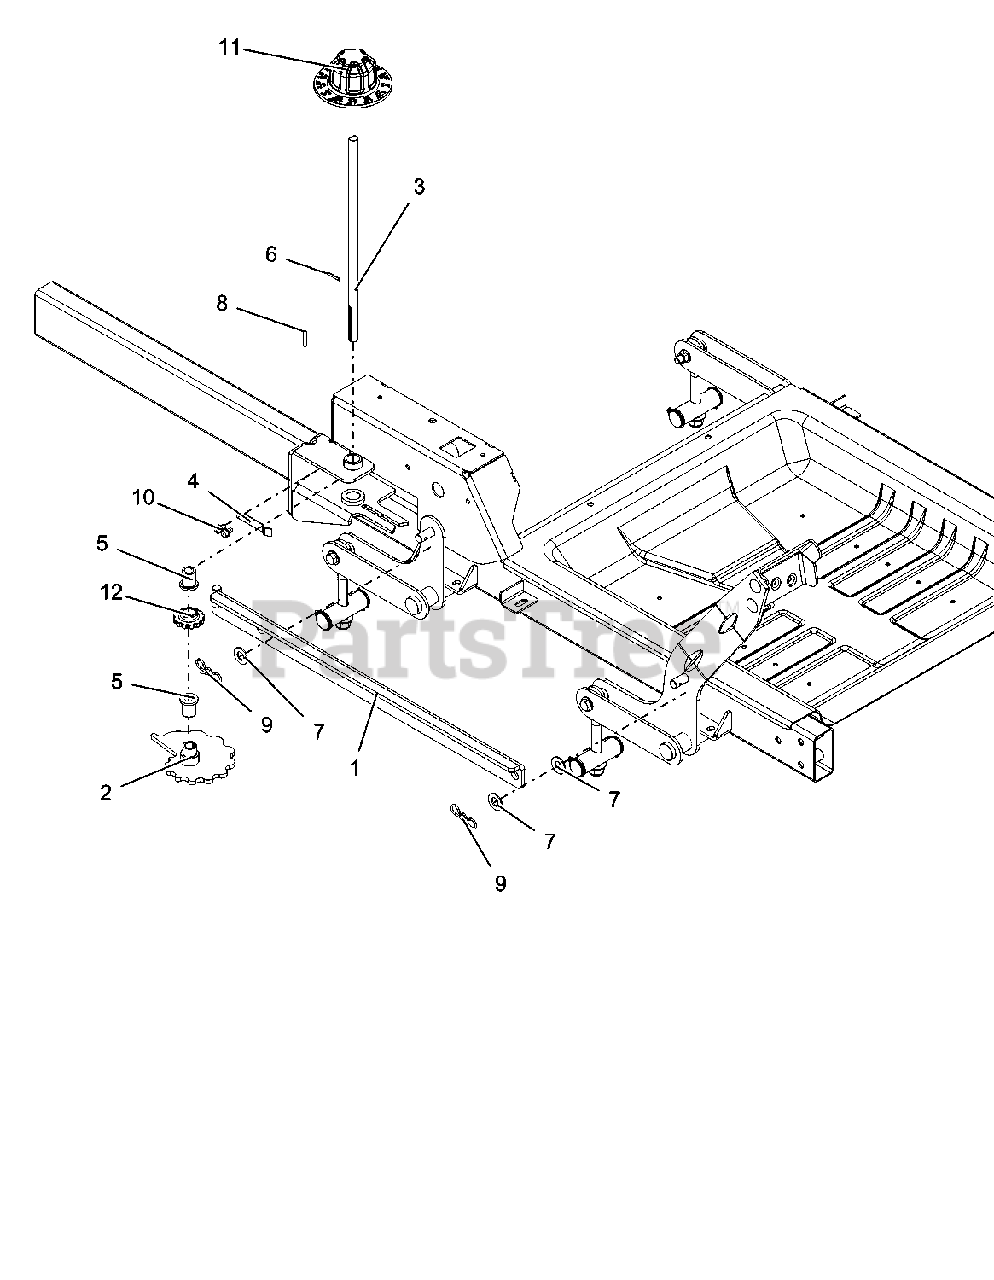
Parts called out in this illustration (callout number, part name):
1	WLDMT, HOC LINK-BLACK
2	WLDMT, HOC CAM
3	CAMSHAFT, HOC
4	ARM, HOC DETENT
5	BUSHING, FLANGE .503X.75X.875X1.0
6	PIN-ROLL .125X1.00
7	WSHR-FL-NYL .518X1.00X.08
8	KEY, 1/8 X 1/8 X 1.0 REV
9	PIN, BOWTIE LOCKING .091X1.875
10	SCR-TAP .25-20X.37 HWH YWZ TR
11	KNOB, HOC
12	CAM, HOC INDEX
